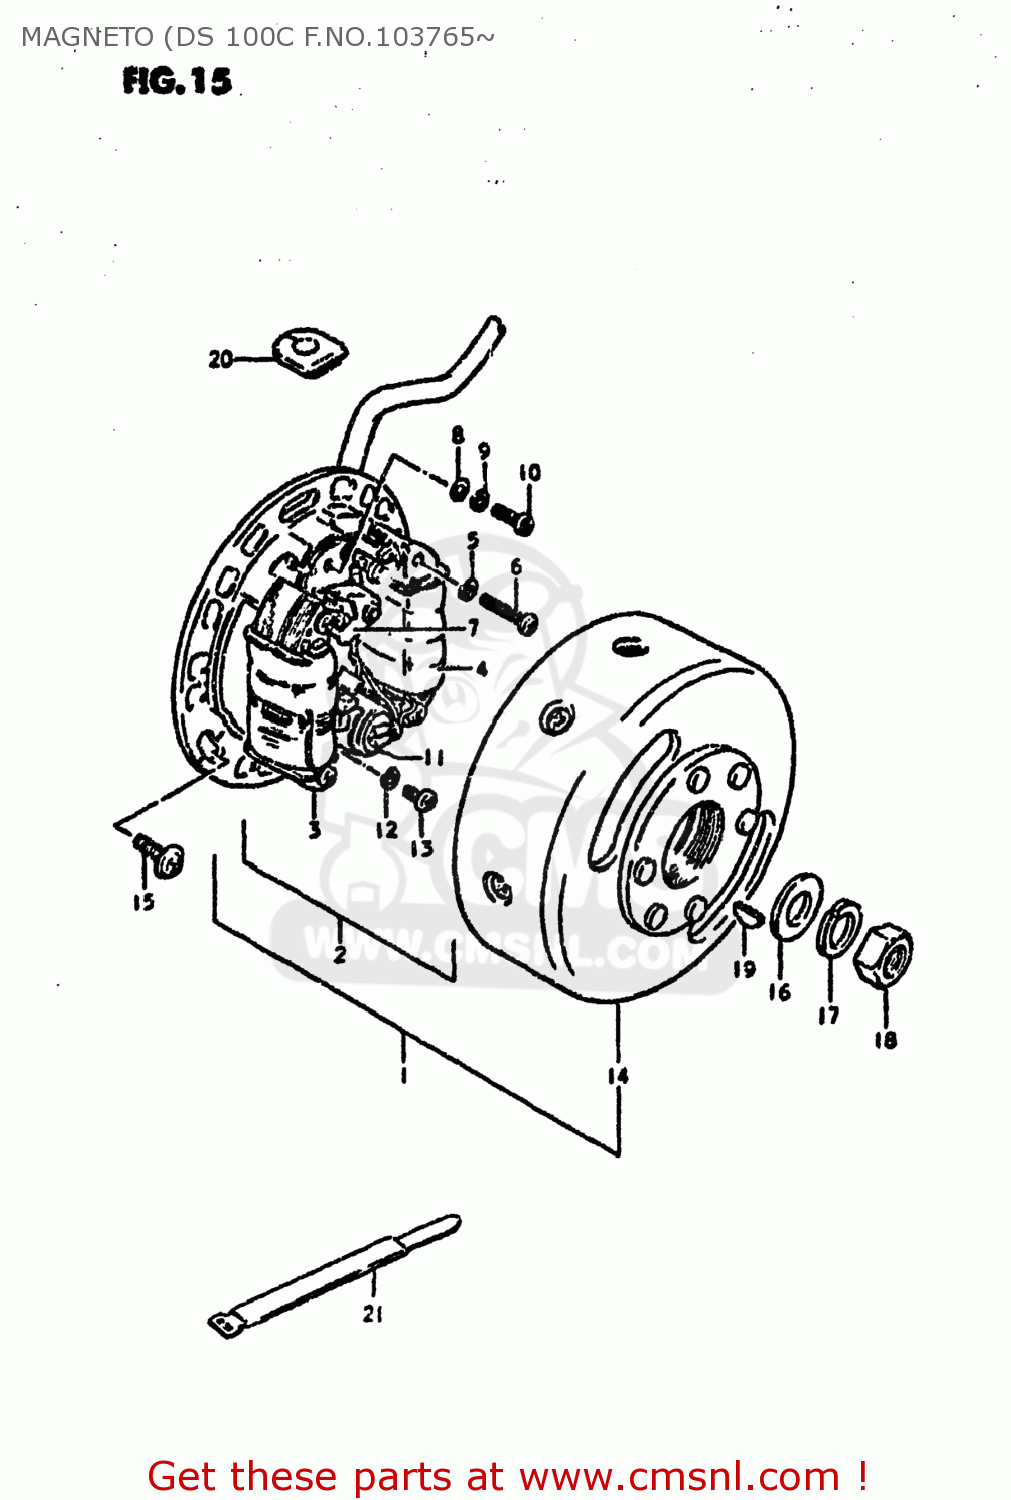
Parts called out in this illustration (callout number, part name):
1	MAGNETO ASSEMBLY
2	STATOR ASSEMBLY
3	COIL,LIGHTING
4	COIL,PRIMARY
5	LOCK WASHER
6	SCREW (4X30)
7	POINT ASSY,CONTACT
8	WASHER
9	LOCK WASHER
10	SCREW(4X10)
11	CONDENSER
12	LOCK WASHER
13	SCREW
14	ROTOR ASSEMBLY
15	SCREW(5X14)
16	WASHER
17	LOCK WASHER
18	NUT (10MM)
19	KEY
20	GROMMET
21	CLAMP
